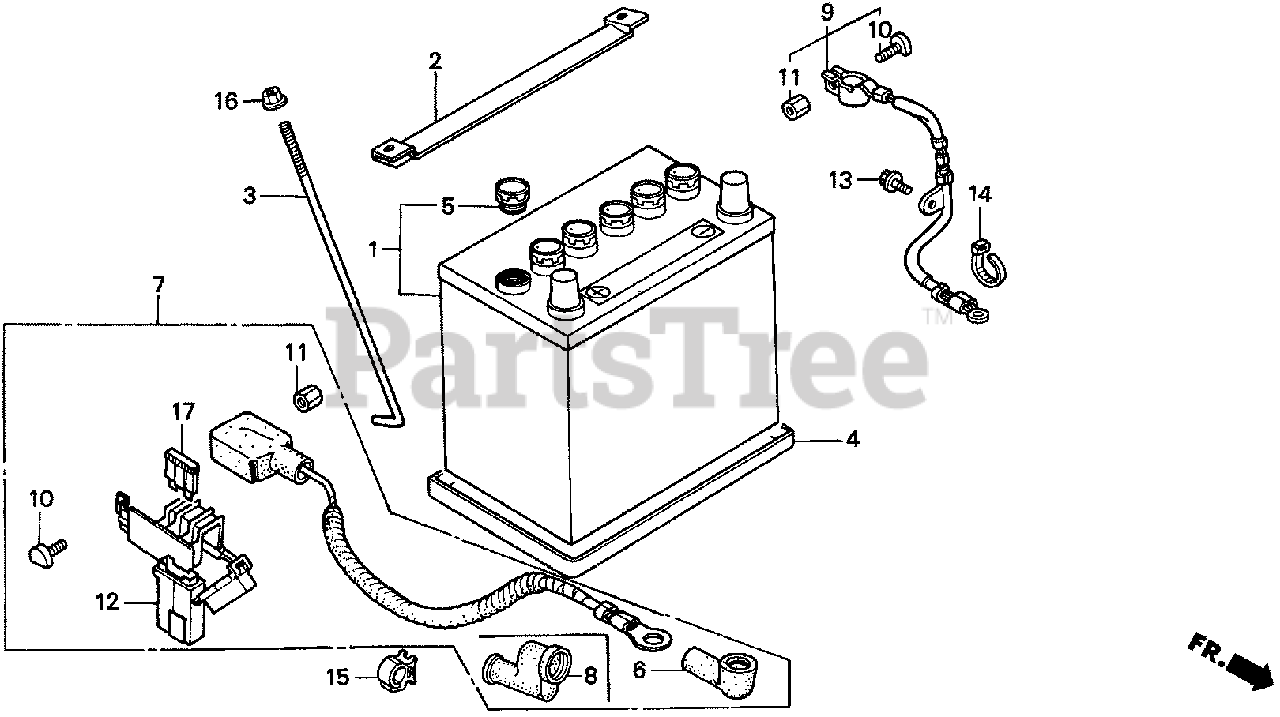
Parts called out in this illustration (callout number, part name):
1	BATTERY ASSY. (32A19RT-S) (YUASA)
1	BTTRY, MF (34A19RT) (S) (MSDS)
1	BATTERY (26A19RT-S) (YUASA)
2	PLATE, BATTERY SETTING
3	BOLT, BATTERY SETTING (220MM)
4	TRAY, BATTERY
5	PLUG, VENT (YUASA)
6	COVER, TERMINAL
7	CABLE ASSY., STARTER (NOT AVAILABLE)
8	COVER, TERMINAL
8	COVER B, MAGNETIC SWITCH (NOT AVAILABLE)
9	CABLE ASSY., GROUND
10	BOLT, BATTERY TERMINAL (SUMITOMO)
10	BOLT, BATTERY TERMINAL
11	NUT, BATTERY TERMINAL (SUMITOMO)
12	CASE, MAIN FUSE
13	BOLT, GROUND (6X12)
14	BAND, CABLE (120MM) (BLACK)
15	CLIP, CABLE (10MM)
16	NUT, FLANGE (6MM)
17	FUSE, BLADE (5A)
